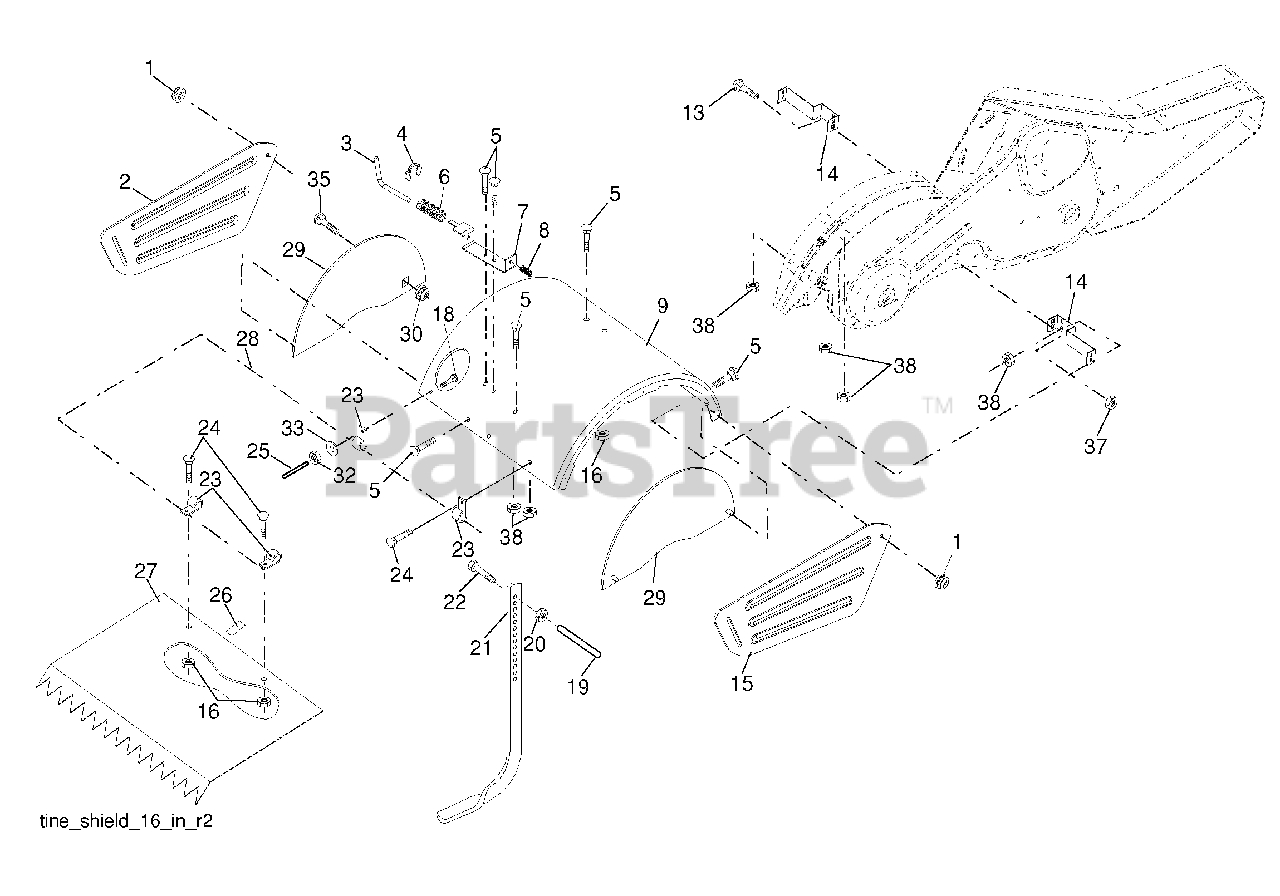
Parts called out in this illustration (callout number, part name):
1	Nut, Lock Hex Flange 5/16-18
2	Shield, Side, Outer L. H.
3	Pin, Stake, Depth
4	Ring, Klip
5	Bolt 5/16-18 x 3/4 ZNC
6	Spring
7	Bracket, Latch
8	Spring, Depth Stake
9	Shield, Tine
13	Bolt, Carriage 5/16-18 x 1-1/4
14	Bracket, Shield Tine
15	Shield, Side, Outer R.H.
16	Nut, Hex Flange 1/4-20 unc
18	Bolt, Carriage 1/4-20 x 1-1/4 Gr. 5
19	Grip
20	Nut, Hex 3/8-16
21	Stake, Depth
22	Bolt, Hex 3/8-16 x 2
23	Hinge
24	Bolt, Carriage 1/4-20 x 1/2 Gr. 5
25	Cap, Vinyl
26	Pad, Idler
27	Shield, Leveling
28	Pin, Hinge
29	Shield, Side
30	Locknut, Flange 5/16-18
32	Nut Fin Hex 1/4-20 unc
33	Washer Lock Hvy Helical 1/4
35	Bolt, Carriage 5/16-18 x 5/8
37	Nut, Lock Hex 5/16-18 unc
38	Nut, Keps 5/16-18 unc
